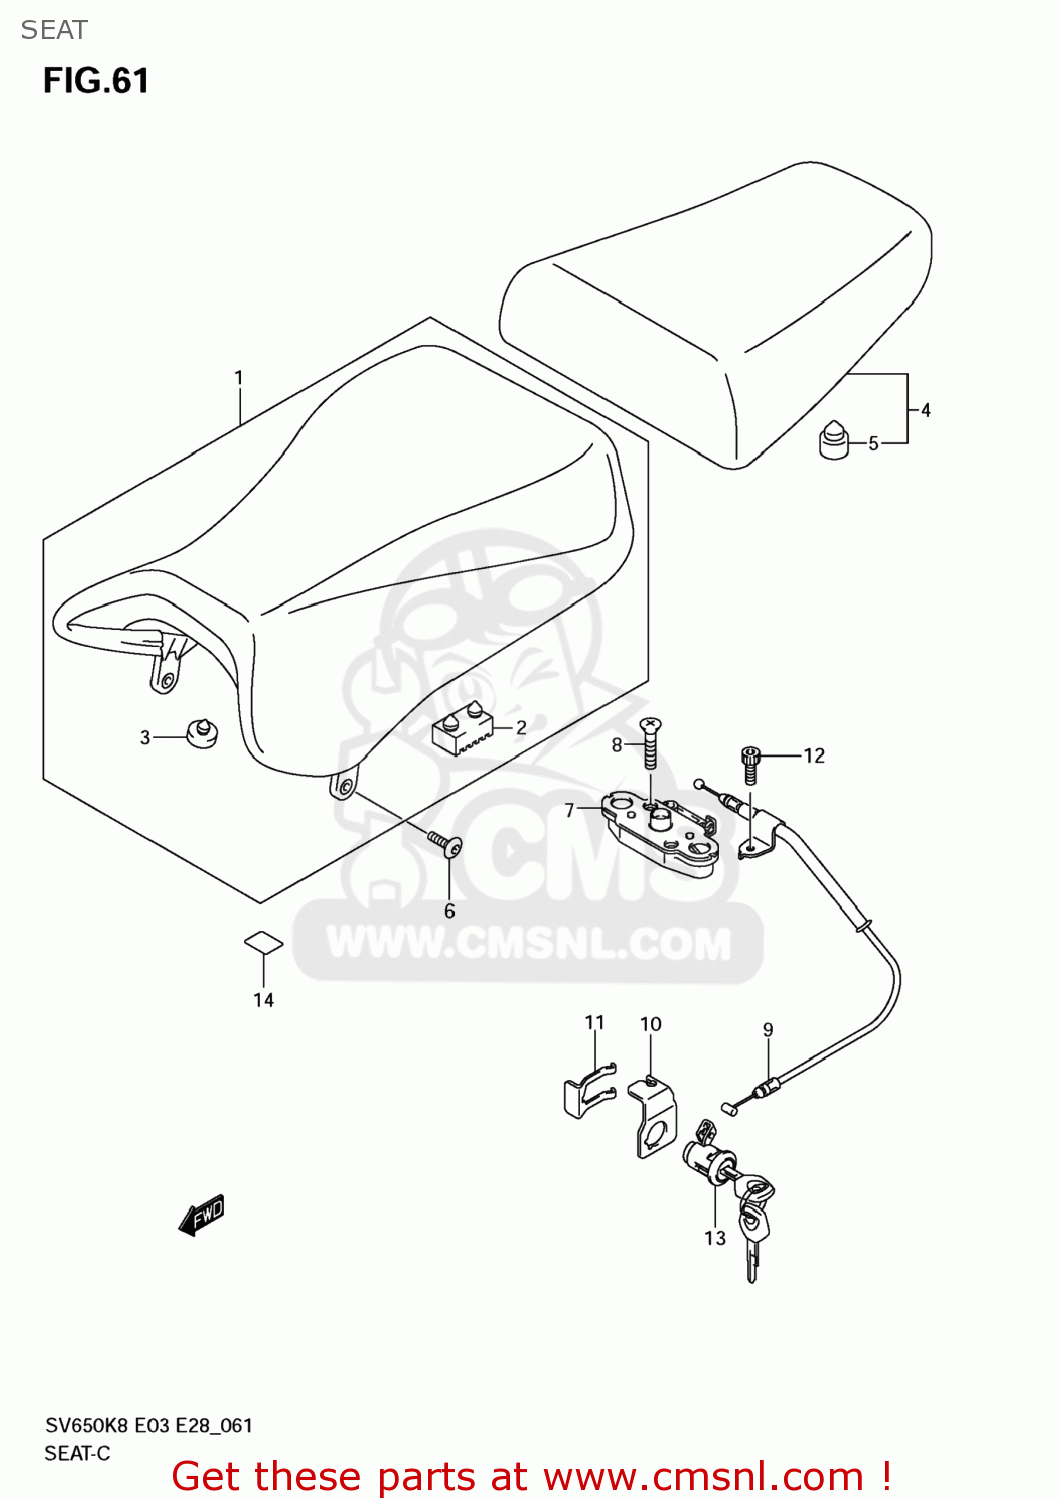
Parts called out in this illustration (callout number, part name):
1	SEAT ASSY
2	CUSHION
3	CUSHION,FR
4	SEAT ASSY,PILLION
5	CUSHION
6	BOLT(6X18)
7	BRACKET,SEAT SUPPORT,RIGHT
8	SCREW
9	CABLE,SEAT LOCK
10	GUIDE,SEAT LOCK CABLE
11	PLATE,SEAT LOCK ASSY
12	BOLT
13	LOCK SET,SEAT
14	TAPE,FUEL TANK
